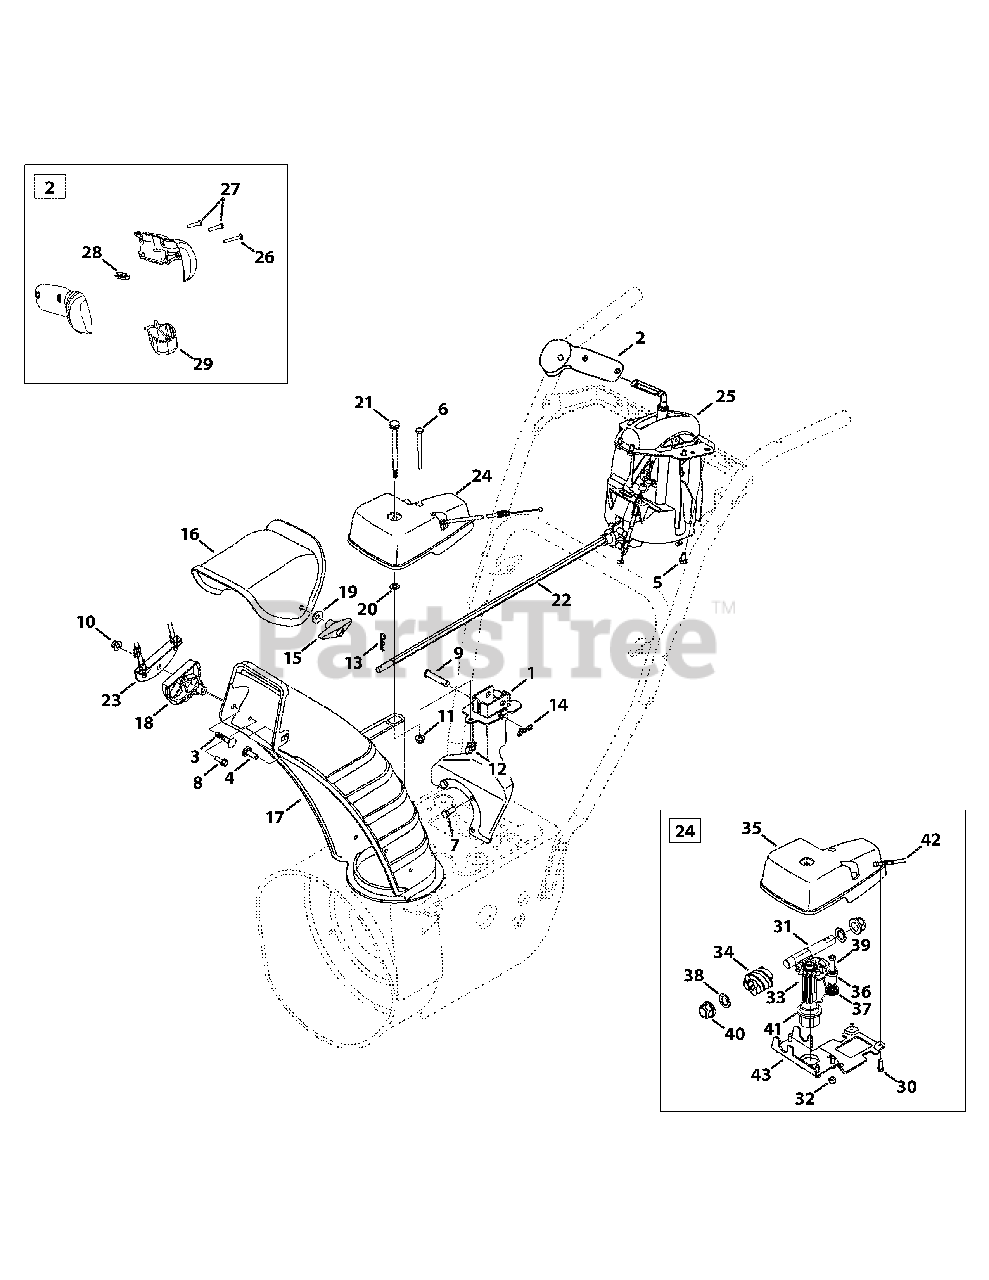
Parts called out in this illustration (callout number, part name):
1	Chute Support Bracket
2	Control Trigger Housing Kit
3	Bolt, Carriage, 5/16-18 x 1.50
4	Bolt, Carrier, 5/16-18 x 1.00
5	Screw, HL, 1/4-15 x 0.50
6	Hex Head Screw, 1/4-20 x 3.00
7	Hex Head Screw, 5/16-24 x .750
8	Screw, HL, 1/4-15 x 0.750
9	Clevis Pin, 3/8 x 1.87
10	Nut, Flangelock, 5/16-18
11	Nut, Flangelock, 1/4-20
12	Wing Nut, 1/4-20
13	Internal Cotter Pin
14	Bow-Tie Cotter Pin
15	Star Knob, 5/16-18
16	Chute, Upper
17	Chute, Lower
18	Cable Guide, Chute Tilt
19	Washer, Flat, .349 x .879
20	Washer, Flat, .25 x .630
21	Screw, Shoulder, .312 x 3.5 x 1/4-20
22	Chute Rod, 3/8 Hex
23	Cable Bracket
24	Gearbox Assembly, Chute Rotation
25	Chute Control, 4-Way Complete
26	Screw, #8 x 1.00
27	Screw, 8-32 x .750
28	Joystick Plug
29	Joystick Trigger
30	Screw, 12-16 x .75
32	Hexlock Nut, 1/4-28
33	Gear, 14 T
34	Worm
35	Gear Cover
36	Pawl Lock
37	Torsion Spring, .721 ID x .474
38	Washer, Flat, .625 x 1.0 x .067
39	Screw, Shoulder, .340 x .950 x 1/4-28
40	Hex Bearing
41	Flange Bearing
42	Cable Lock
43	Gear Bracket
